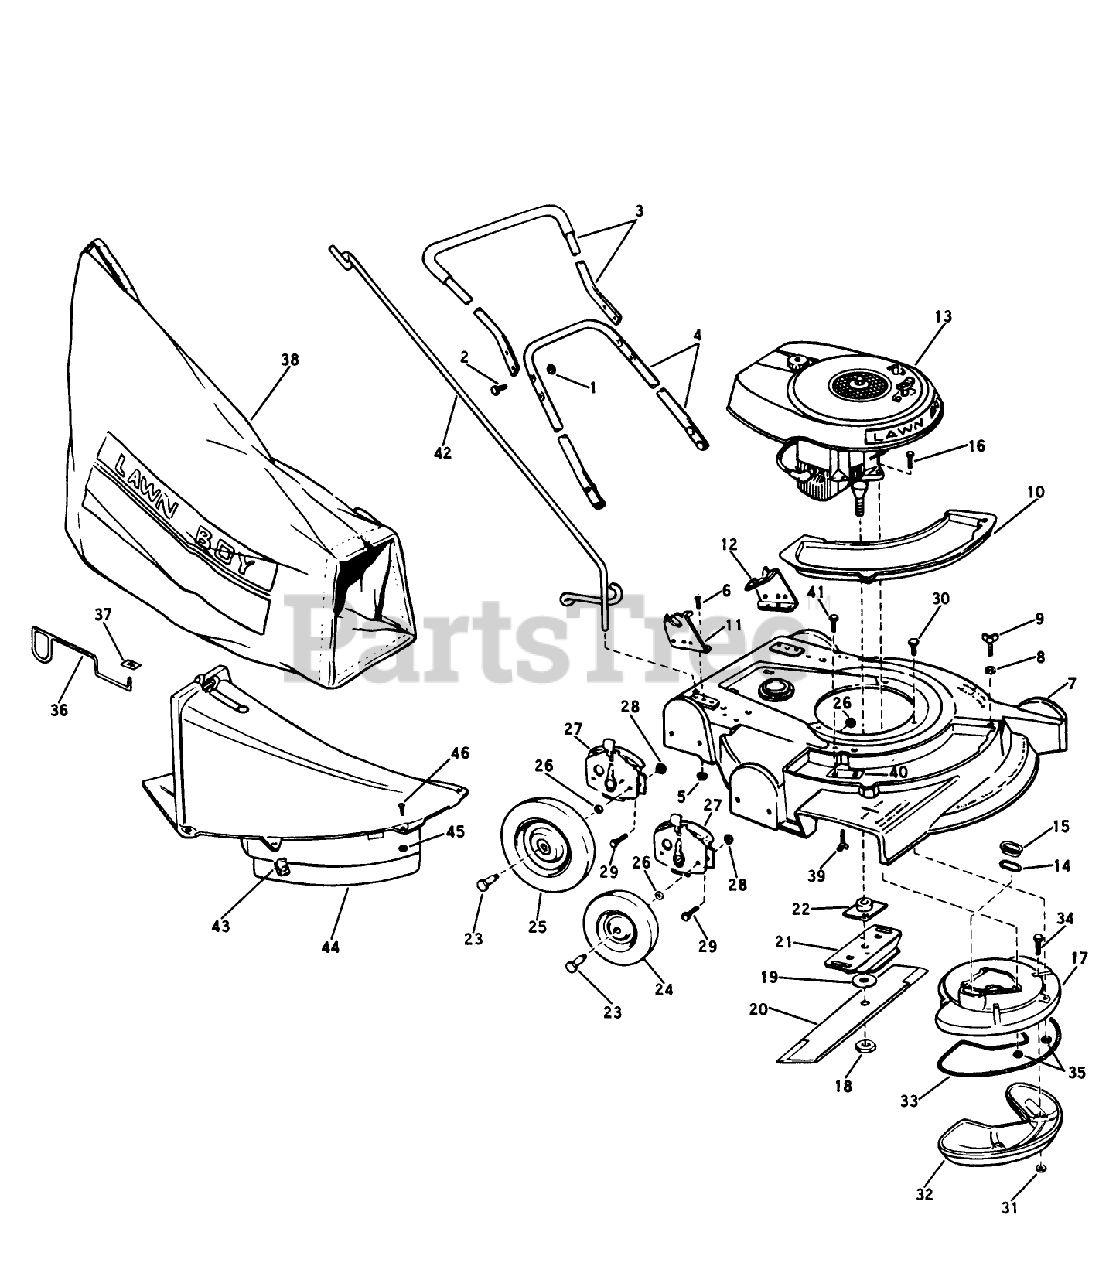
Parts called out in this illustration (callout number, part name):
3	Handle Grip Assy. Top
6	SCREW S
8	Plastic-Grommet
14	Gasket-Exhaust
18	NUT-BLADE
20	Blade-21"
22	PLATE AND COLLAR ASM
23	BOLT WHEEL
26	WASHER WROUGHT
31	LOCKNUT E
38	89802 LB WHOLE GOODS
43	SPEED NUT ARDEN
44	Chute Skirt Assembly (Includes Hardware)
